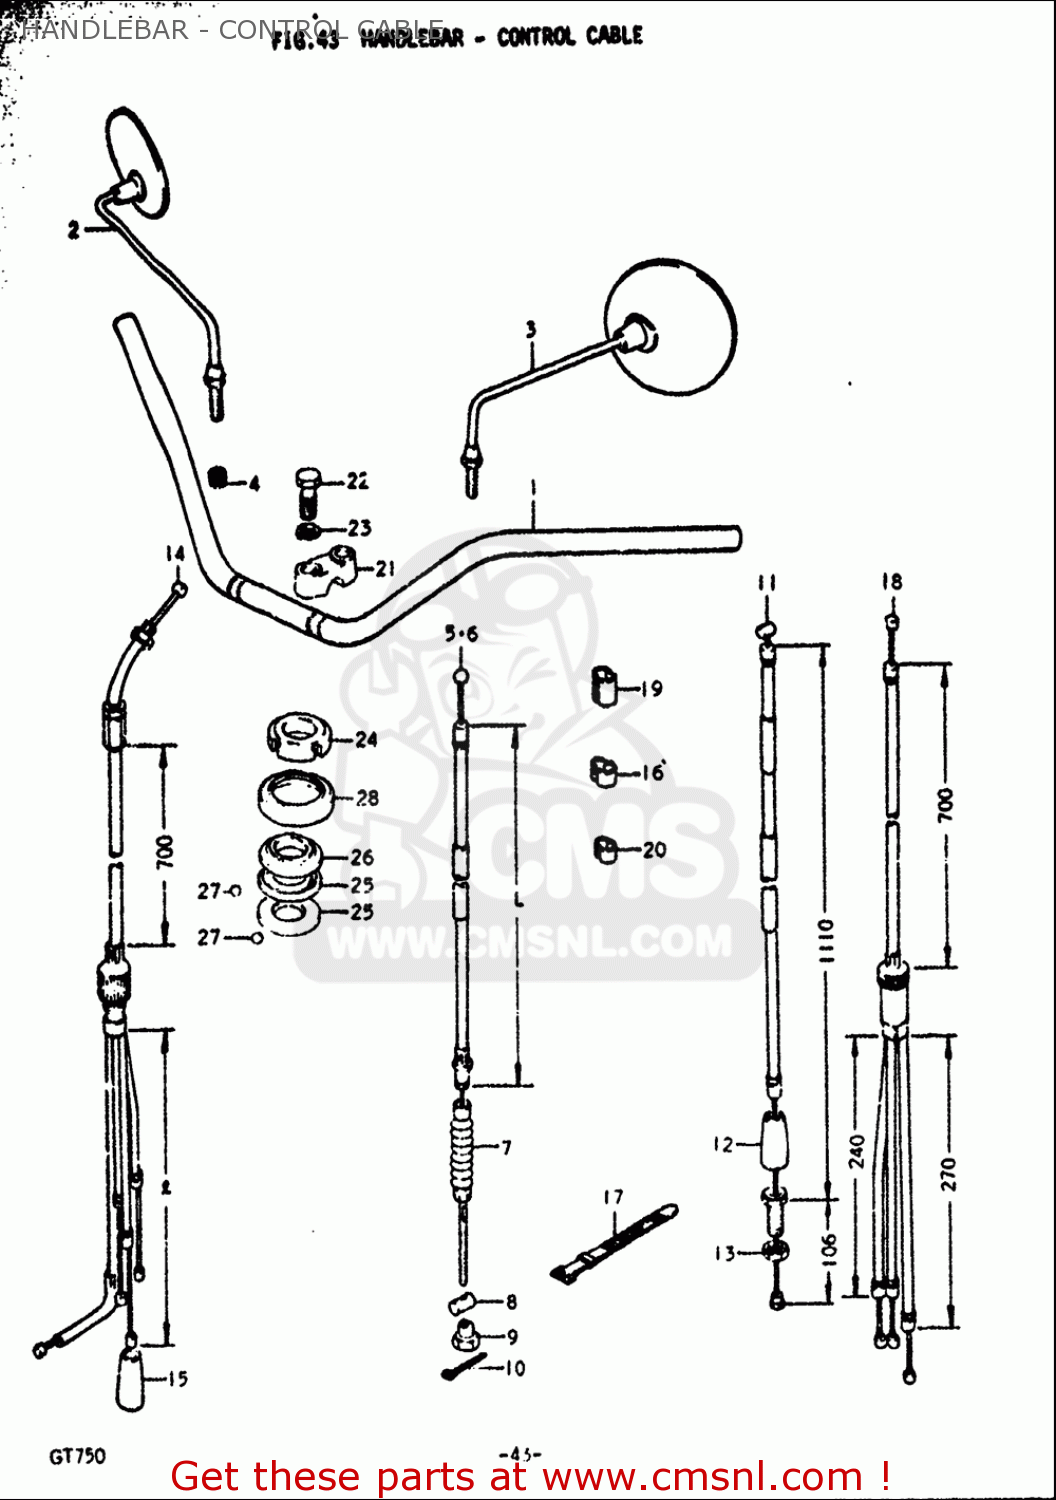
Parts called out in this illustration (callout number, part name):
1	HANDLEBAR
2	MIRROR ASSY,RE
3	MIRROR ASSY,LEFT
5	CABLE,FR BRAKE,R
7	SEAL,DUST
8	PIN(13X18)
9	NUT
10	PIN
11	WIRE,CLUTCH
13	NUT
15	SEAL,DUST(7X18X30)
16	CLIP
17	CLAMP(L:120)
19	CLIP
20	CLIP
21	HOLDER,HANDLE UPR
22	BOLT
23	WASHER,LOCK
24	NUT,STEERING STEM(25X44X10)
25	LACE,STEERING INNER LWR
26	LACE,STEERING OUTER UPR
27	BALL
28	DUST SEAL,STEERING UPR
